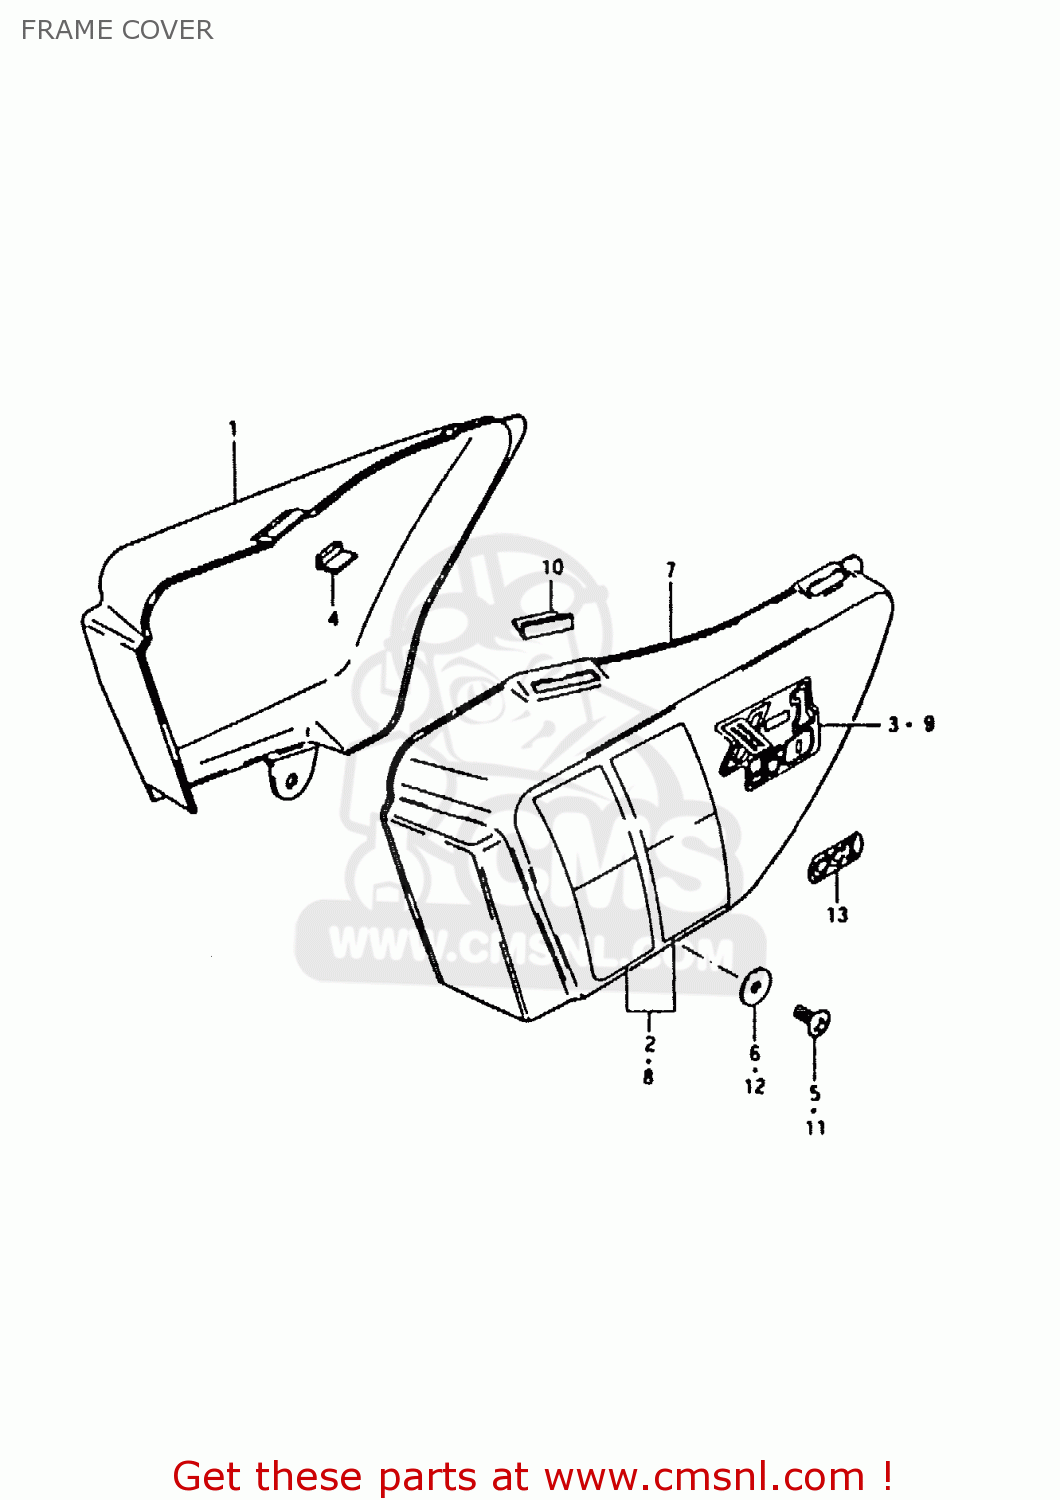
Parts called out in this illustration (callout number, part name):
1	COVER, FRAME RH (BLACK)
2	TAPE, STRIPING RH
3	EMBLEM, LH
4	CUSHION,FRAME COVER
5	SCREW
6	WASHER
7	COVER, FRAME LH (BLACK)
8	TAPE, STRIPING LH
9	EMBLEM, LH
10	CUSHION,FRAME COVER
11	SCREW
12	WASHER
13	EMBLEM,CCIS
